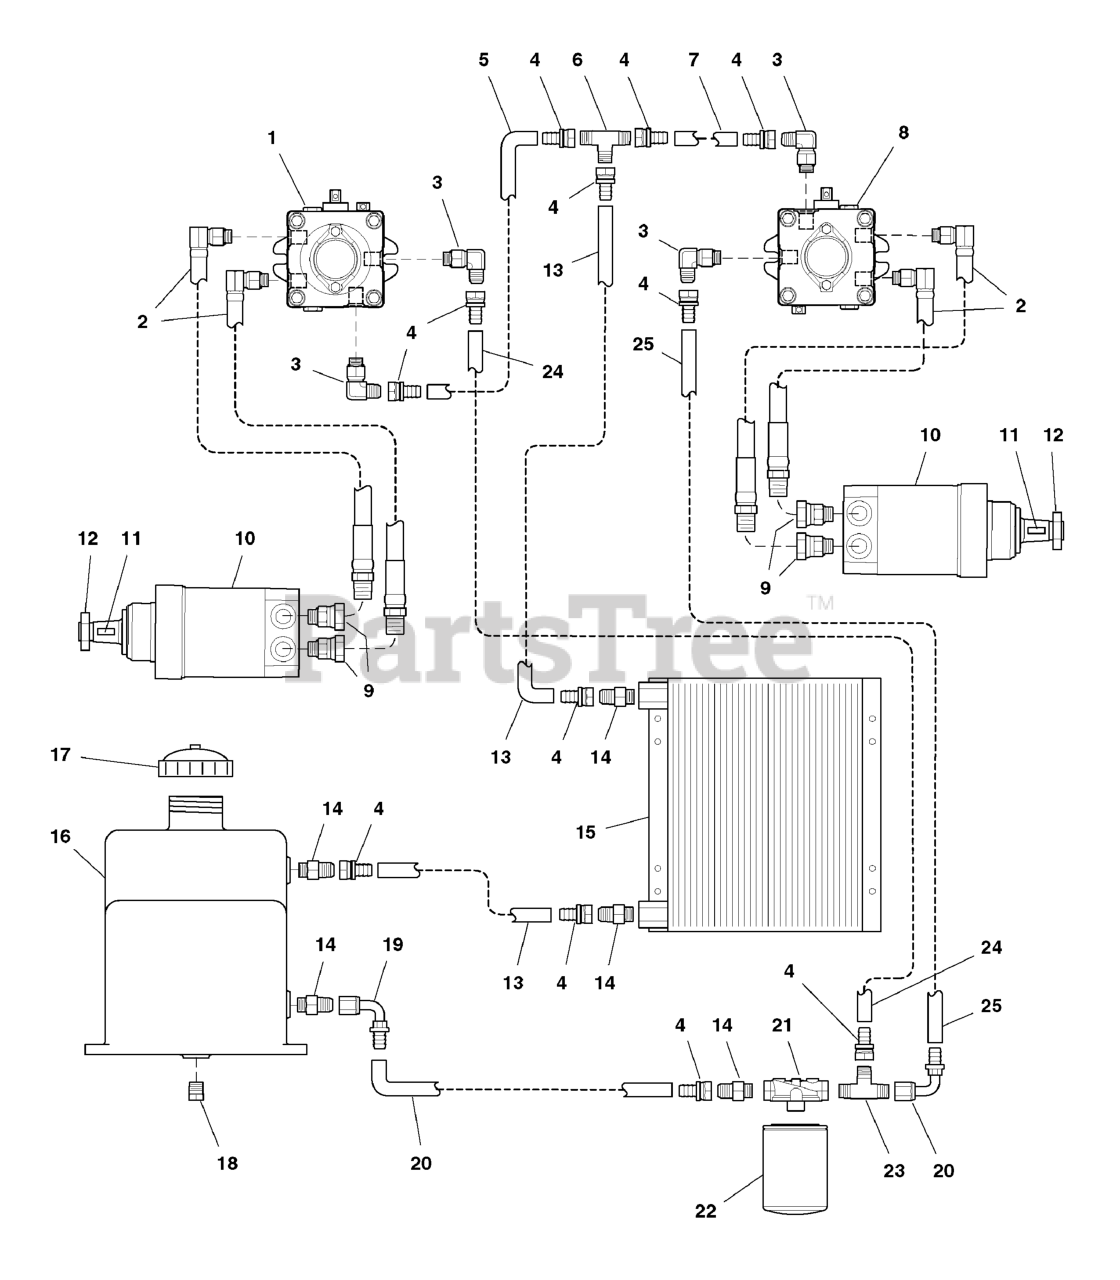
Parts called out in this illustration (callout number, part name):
1	HYDRAULIC PUMP - RH
2	REPLACE WITH 5413138 + 5022599, HYDRAULIC HOSE ASSEMBLY + FITTING
3	FITTING, O-Ring, 90 Deg.
4	FITTING, JIC #8, Straight
5	HOSE, Hydraulic, 40"
6	FITTING, TEE, JIC #8
7	HOSE, 15" Long
8	HYDRAULIC PUMP - LH
9	FITTING, 7/8" O-Ring Straight Swivel
10	HYDRAULIC WHEEL MOTOR, Complete
11	KEY
12	NUT & COTTER PIN
13	HOSE, Hydraulic, 34"
14	FITTING, NPT - JIC #8
15	OIL COOLER
16	HYDRAULIC OIL RESERVOIR
17	CAP, Reservoir
18	PLUG, 1/2" NPT
19	FITTING, 90 Deg. JIC #8
20	HOSE, 7"
21	FILTER HEAD
22	FILTER, HYDRAULIC, SERVICE PART (PKG)
23	FITTING, TEE, JIC #8, NPT
24	HOSE, Hydraulic, 38"
25	HOSE, Hydraulic, 24"
